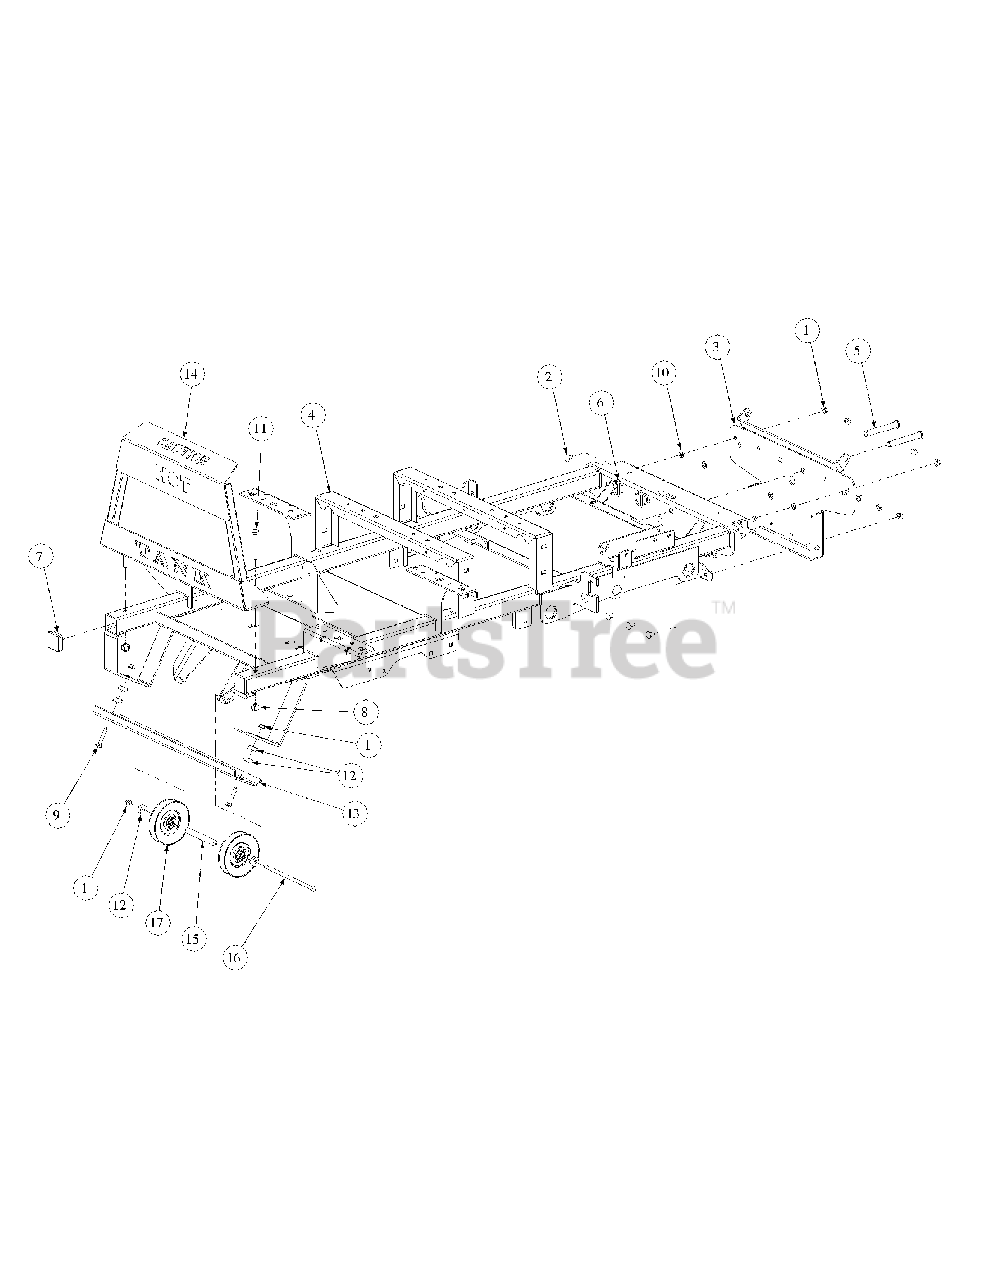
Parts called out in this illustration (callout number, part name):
1	Hex Nut, 3/8-16 Flange Lock
2	Carriage Bolt, 3/8-16 x .75 Long
3	Bracket Assembly, Frame, Front
4	Frame Assembly
5	Clevis Pin, .625 Dia x 4.375 Long
6	Linch Pin, 3/16 Dia.
7	Plug, Square Tube
8	Lock Nut, Nylon Insert, 1/2-13
9	Carraige Bolt, 3/8-16 x 1.75
10	Push Retainer, 3/8
11	Hex Head Cap Screw, 1/2-13 x 3.00
12	Spacer, .406 ID x 1.00 OD x .380
13	Guard Bracket
14	Muffler Guard Assembly
15	Spacer, .385 ID x .625 OD x 4.89
16	Hex Head Cap Screw, 3/8-16 x 8.50
17	Idler Pulley, 5.06 Dia.
